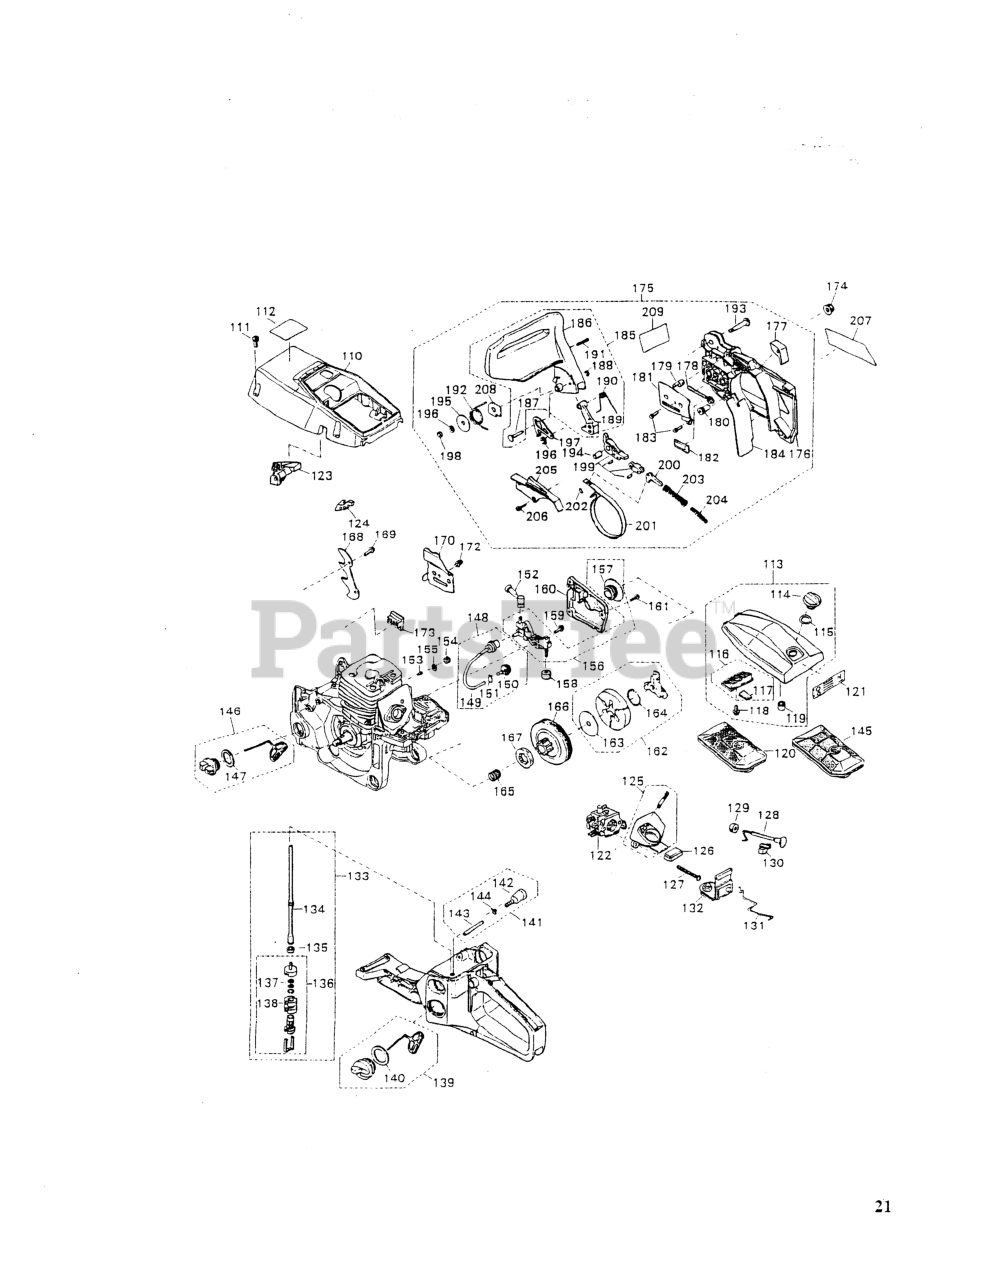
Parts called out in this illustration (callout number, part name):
110	COVER, CYLINDER (RPLS-31112)
111	SCREW (REPLACES 2616-24320)
115	GASKET, KNOB
116	CLEANER COMP
118	SCREW
120	CLEANER, AIR
122	CARBURETOR-A (WT-296-1)
125	MANIFOLD COMPLETE
126	SUPPORTER
128	ROD, CHOKE
130	GUIDE
131	ROD, THROTTLE
136	FILTER ASSY
139	CAP ASSEMBLY
140	GASKET
141	BREATHER ASSEMBLY
142	BREATHER (USE 2670-34500)
144	CLIP (REPLACES 2841-31280)
145	CLEANER, AIR (FLOCKED)
147	GASKET
148	OIL PIPE ASSEMBLY
151	CLIP (REPLACES 2841-31280)
152	PIPE, OIL OUTLET
153	VALVE (RPLS -23120)
154	SEAL, BREATHER
155	CLIP
157	GEAR
158	SEAL
159	SCREW
160	COVER, PUMP
161	SCREW
163	PLATE, THRUST
164	SPRING
165	BEARING (RPLS 2670-51310)
166	DRUM, CLUTCH (RPLS 2670- )
167	RIM SPROCKET, .325, 7-TOOTH
168	SPIKE
169	SCREW (REPLACES 2616-24320)
170	PLATE (REPLACES 2670-25422)
173	GUIDE, CHAIN
174	NUT
177	STOPPER
178	SCREW
179	NUT
180	GEAR
182	GUIDE, CHAIN
183	SCREW
184	PROTECTOR
185	GUARD COMP.
187	PIN, STOPPER
188	RING, SNAP, M3
189	WEIGHT, ACTION
190	848-C8E-54D1
191	PIN, SPRING
192	SPRING, RETURN
193	PIN
195	WASHER
196	RING, SNAP, M4
197	PLATE (RPLS 2670-54241)
199	LEVER (REPLACES 2670-54301)
200	ARM, SLIDE
201	BAND, BRAKE
202	PIN
203	SPRING, BRAKE (RPLS. 50030121)
205	COVER (REPLACES -54620)
206	SCREW
207	LABEL, CHAIN COVER
